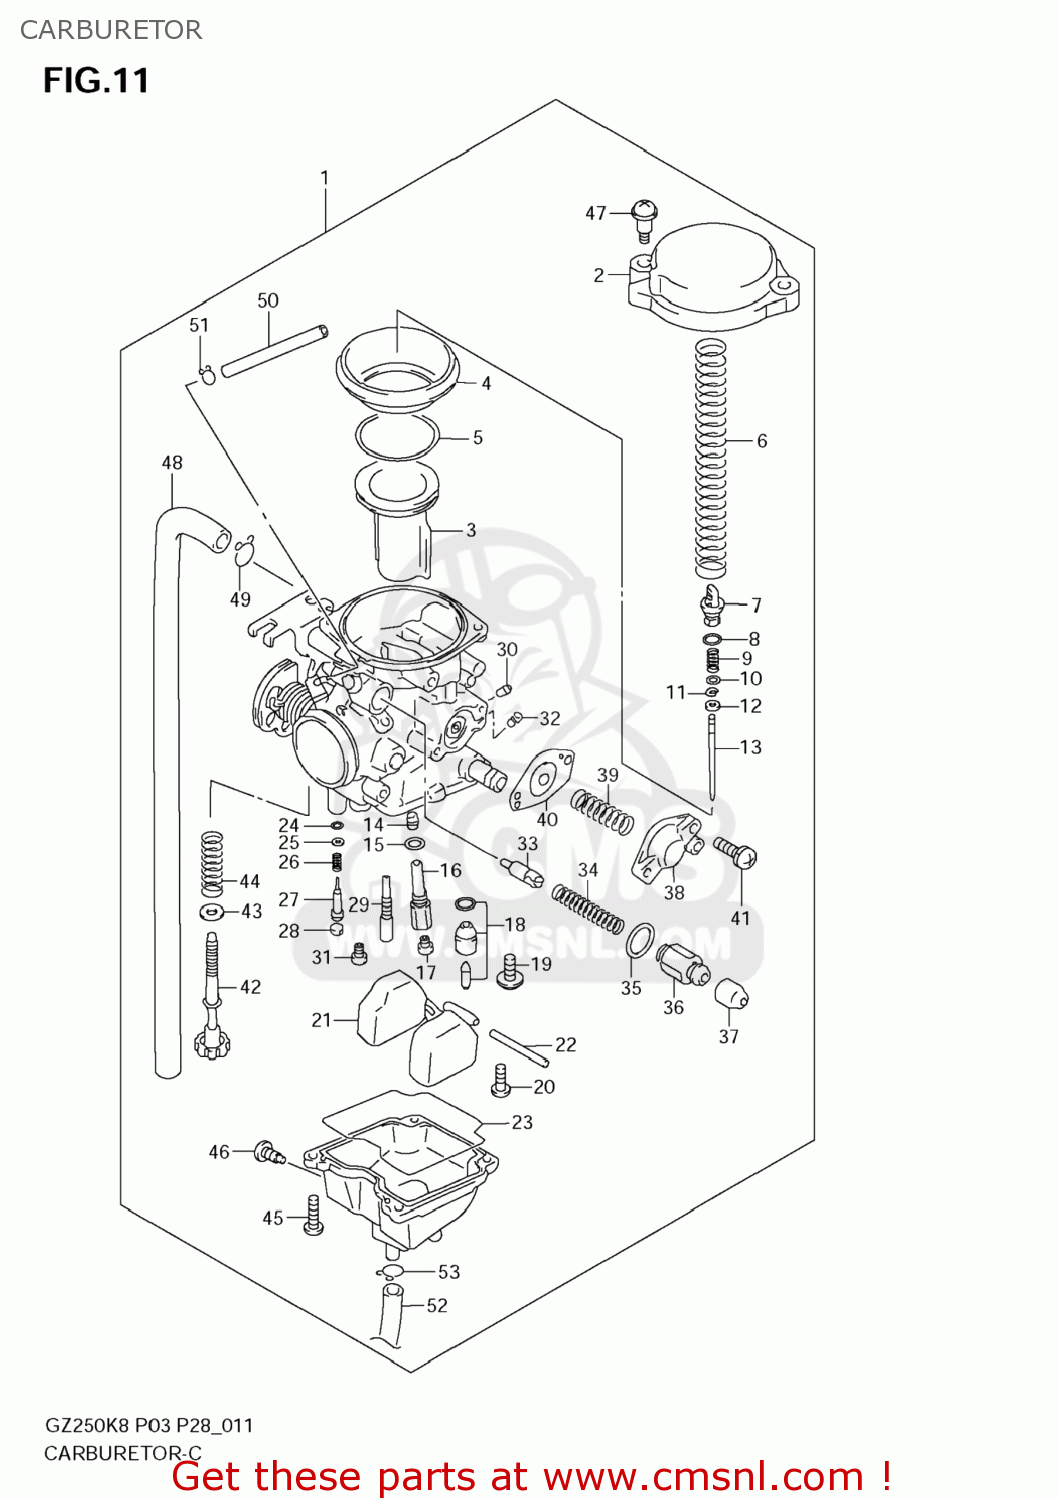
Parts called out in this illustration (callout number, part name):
1	CARBURETOR ASSY
2	COVER,DIAPHRAGM
3	VALVE,PISTON
4	DIAPHRAGM
5	RING
6	SPRING
7	HOLDER
8	O RING(D:1.9,ID:4.8)
9	SPRING
10	WASHER
11	E RING,MULTIPLE JET NOZZLE
12	RING
13	NEEDLE,JET
14	JET,NEEDLE(P-0M)
15	O RING
16	HOLDER,JET
17	JET,MAIN(120)
18	VALVE ASSY,NEEDLE
19	SCREW
20	SCREW
21	FLOAT ASSY
22	PIN,FLOAT
23	GASKET (NAS)
24	O RING,PILOT AIR SCREW
25	WASHER
26	SPRING,THROTTLE SCREW
27	ADJUSTER
28	PLUG
29	JET,PILOT(17.5)
30	JET,MAIN(87.5)
31	JET,MAIN(52.5)
32	JET,PILOT AIR(120)
33	PLUNGER
34	SPRING
35	O RING
36	HOLDER,GUIDE
37	CAP
38	COVER ASSY
39	SPRING
40	DIAPHRAGM ASSY
41	SCREW
42	SCREW,ADJUST
43	PACKING (NAS)
44	SPRING
45	SCREW
46	SCREW,DRAIN
47	SCREW
48	HOSE
49	CLIP
50	HOSE
51	CLIP
52	HOSE(4.5X8X650)
53	CLIP
